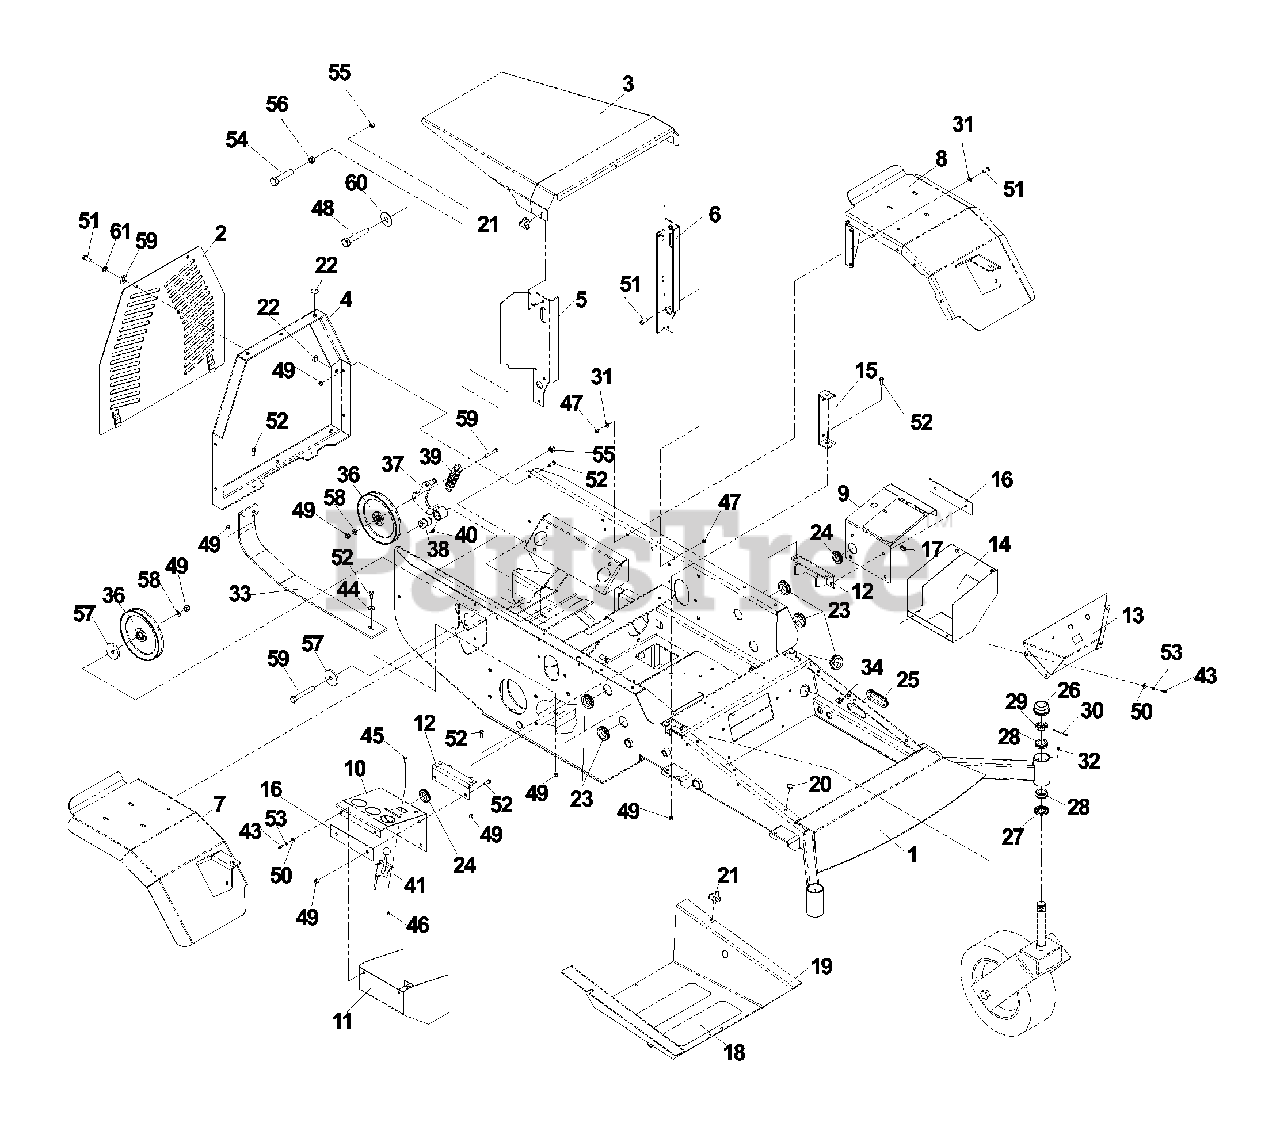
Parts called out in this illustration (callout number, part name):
1	Frame w/decals
2	Panel, back, w/decals
4	Frame, rear
5	Support, right
6	Support, left
7	Fender, right
8	Fender, left
9	Panel, top left
10	Console, top
11	Console, bottom
12	Bracket, angle
14	Console, bottom
17	Latch, magnetic
18	Pad, abrasive
19	Pan, floor
20	Stop, rubber
21	Knob w/stud
22	Grommet, bumper
26	Cap, grease
29	Nut, 1-14, slotted jam
30	Pin, cotter, 1/8 x 2
31	Washer, 5/16, SAE
33	Plate, skid
36	Idler
40	Zerk
41	Cable, throttle
43	Screw, 1/4-20 x 5/8, self-tapping
44	Washer, 3/8
45	Bolt, #10-24 x 1/2
46	Nut, #10-24, nyloc
47	Nut, 5/16-18, nyloc
48	Bolt, 1/2-20 x 2 1/2
49	Nut, 3/8-16, nyloc
50	Washer, 1/4
51	Bolt, 5/16-18 x 1
52	Bolt, 3/8-16 x 1
53	Lockwasher, 1/4
54	Bolt, 1/2-20 x 2, Gr.8,
55	Nut, 1/2-20, nyloc,
56	Nut, 1/2-20,
57	Washer, heavy
58	Washer, 3/8
59	Washer, 5/16
60	Washer, 1/2
61	Lockwasher, 5/16
